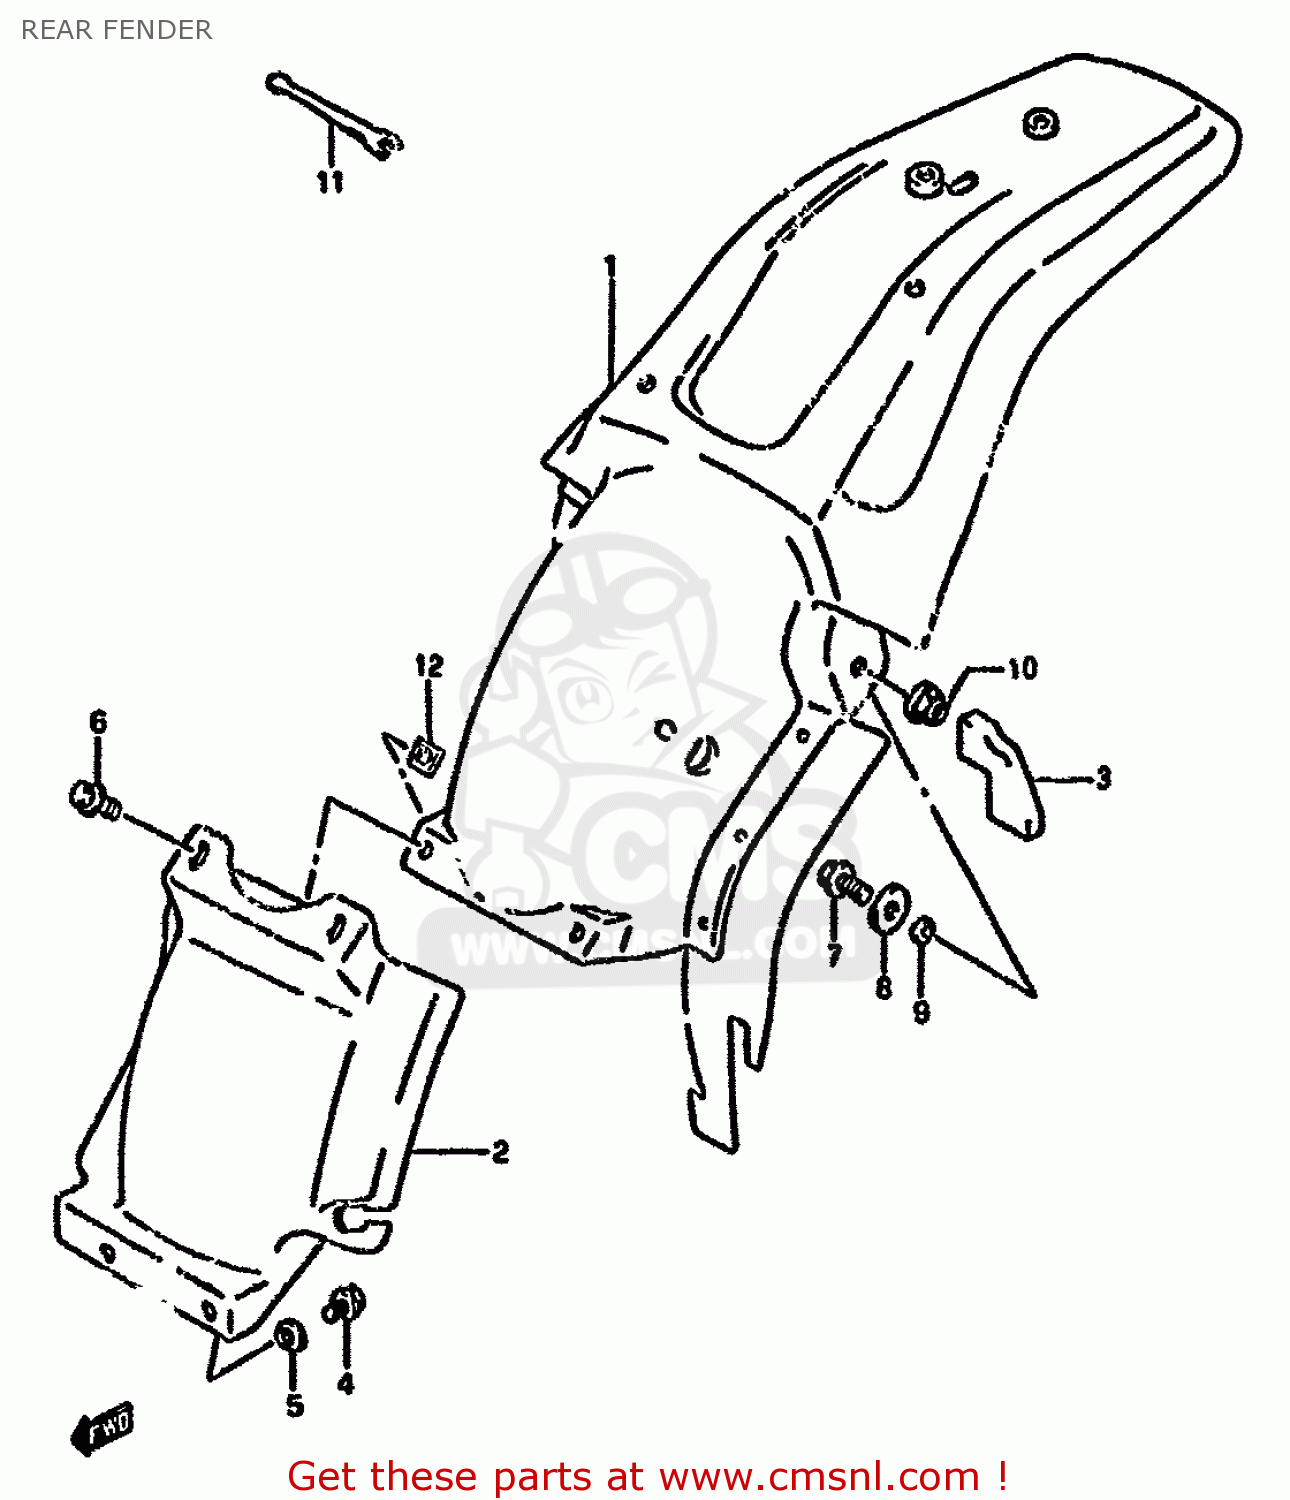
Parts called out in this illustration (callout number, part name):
1	BODY ASSY,REAR FENDER REAR (YELLOW)
2	BODY,RR FENDER FR
3	CUSHION,RR FENDER,L
4	BOLT
5	WASHER
6	BOLT
7	BOLT
8	WASHER (8.5X20X1.6)
9	SPACER (8.1X12X3)
10	NUT
11	SPANNER,OPEN
12	NUT,RR FENDER
